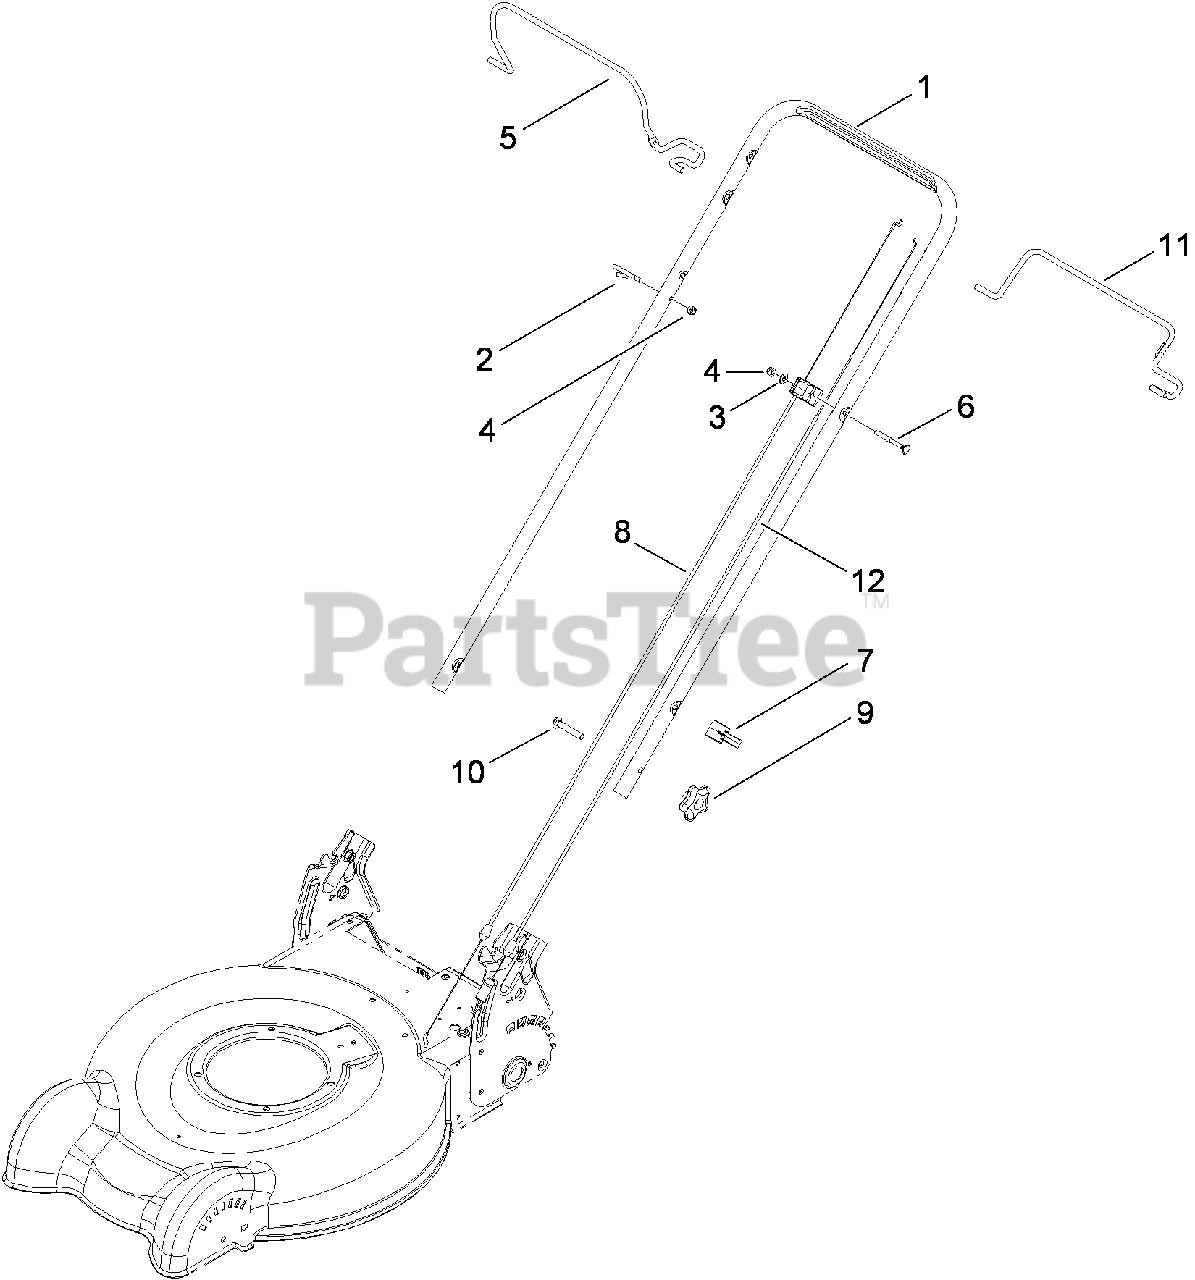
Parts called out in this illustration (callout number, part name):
1	HANDLE
2	GUIDE-ROPE
3	WASHER-FLAT
4	NUT-LOCK, NI
5	BAIL-BRAKE, 2-BAIL FLAT
6	SCREW-HANDLE
7	Guide-Cable
8	CABLE-BRAKE
9	KNOB-LOCKING
10	Screw-CARR
11	BAIL-TRACTION, 2-BAIL FLAT
12	CABLE-TRACTION
